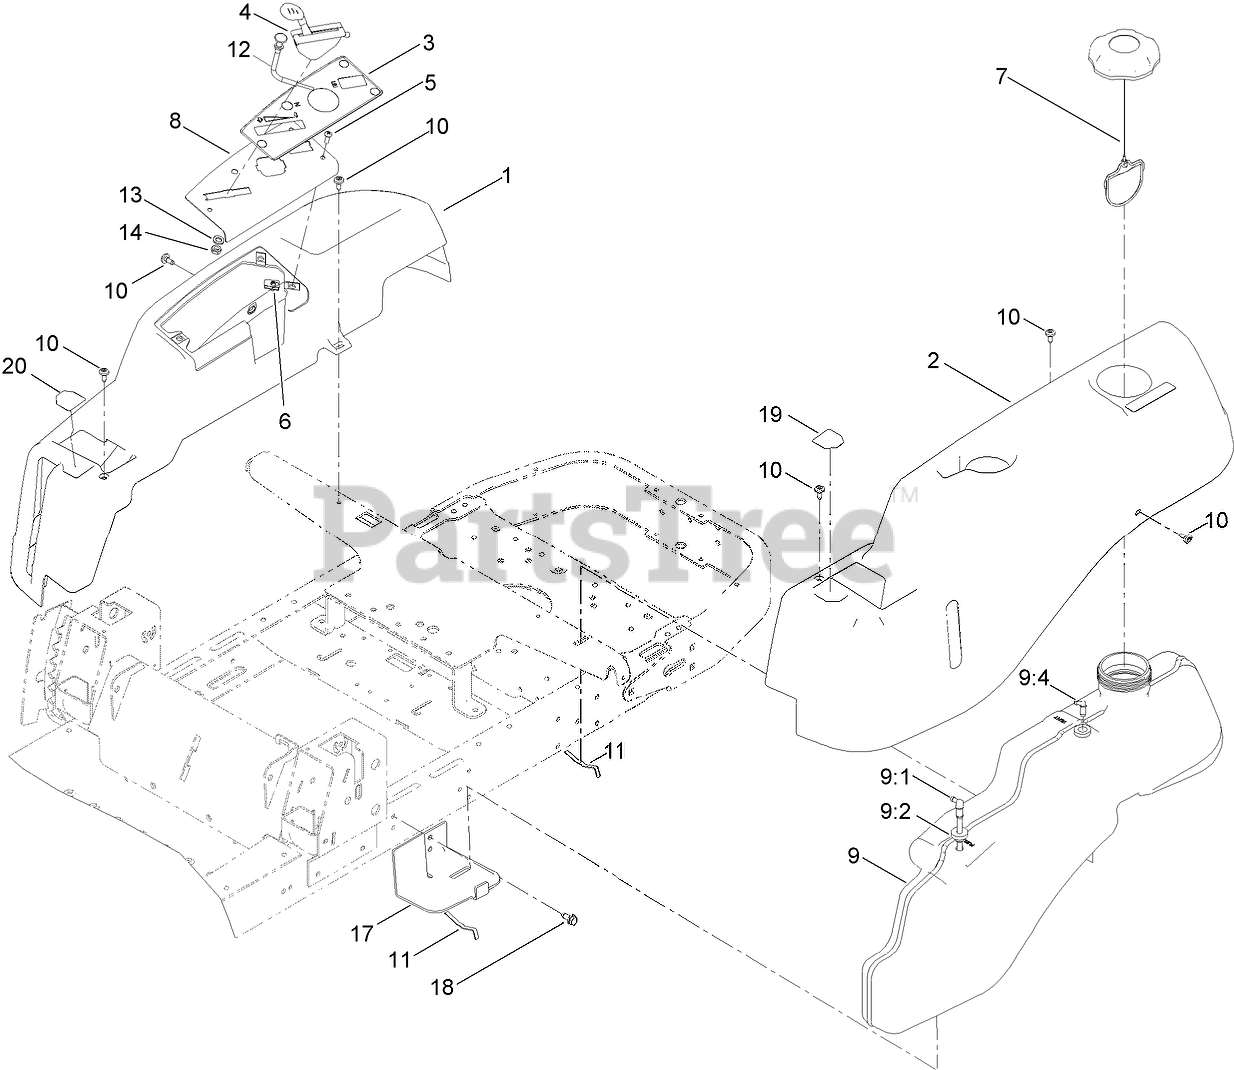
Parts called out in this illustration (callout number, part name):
1	POD-RH
2	POD-LH
3	DECAL-PANEL, CONTROL
4	CABLE-THROTTLE (45.0 IN)
5	SCREW-PRH
7	CAP-FUEL, RATCHETING
8	PLATE-CONTROL
9	FUEL TANK ASM
9:1	CONNECTOR-ELBOW, 90 DEG
9:2	BUSHING
9:4	FITTING-PLASTIC
10	SCREW-SHOULDER
11	SPRING
12	CABLE-CHOKE
13	WASHER-LOCK
14	NUT-HJ
17	SUPPORT-TANK, FRONT
18	SCREW-HWHTF
19	DECAL-CONTROL LEVER, LH
20	DECAL-CONTROL LEVER, RH
